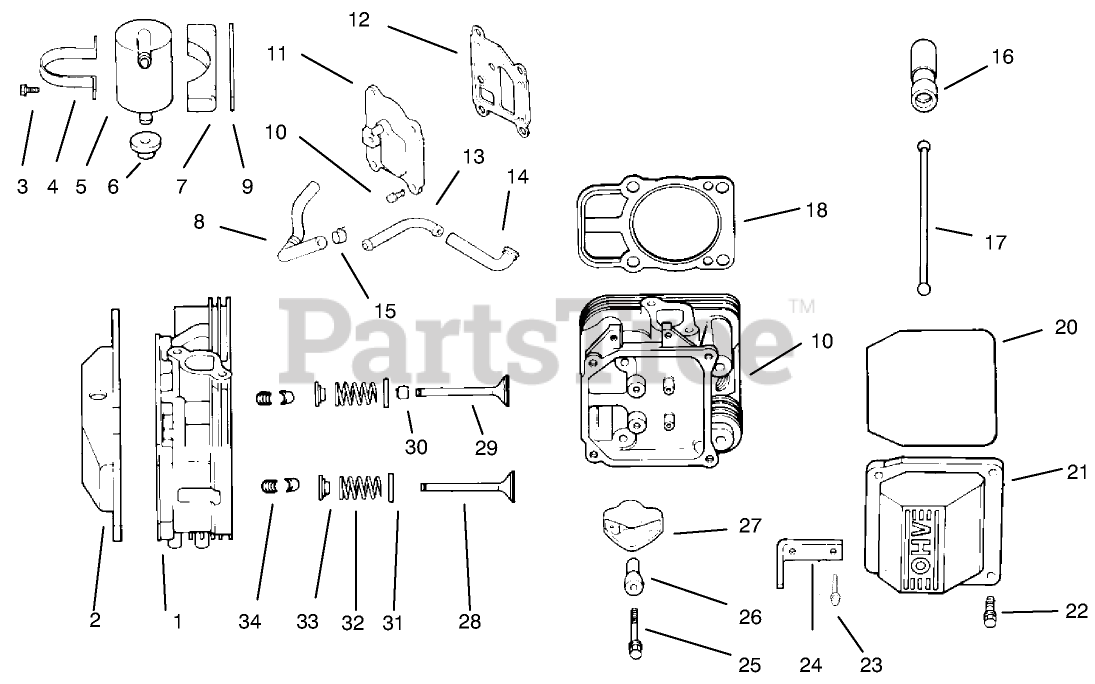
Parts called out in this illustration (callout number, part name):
1	Head ASM-#1 Cylinder (Only On: 72103, 72083)
2	Cover-Rocker (Only On: 72103)
3	Kit-Breather INCL 4 (Only On: 72103)
4	Grommet-Rubber (Only On: 72103)
5	Cover-Breather (Only On: 72103)
7	Hose-Breather (Only On: 72103)
8	Kit-Retainer
9	Cap-Valve Spring
10	Spring-Valve
11	Retainer-Spring
12	Valve-Exhaust
13	Valve-Intake
14	Seal-Valve Stem
15	Fitting (Only On: 72103)
16	Hose-Breather (Only On: 72103)
17	Lifter-Valve
18	Rod-Push (Only On: 72103,72083)
19	Gasket-Cylinder Head
20	Head ASM-#2 Cylinder (Only On: 72103, 72083)
21	Arm-Rocker (Only On: 72103,72083)
22	Ball-Rocker Pivot
24	Cover-Rocker (Only On: 72103)
25	Screw
27	Strap-Lifting
